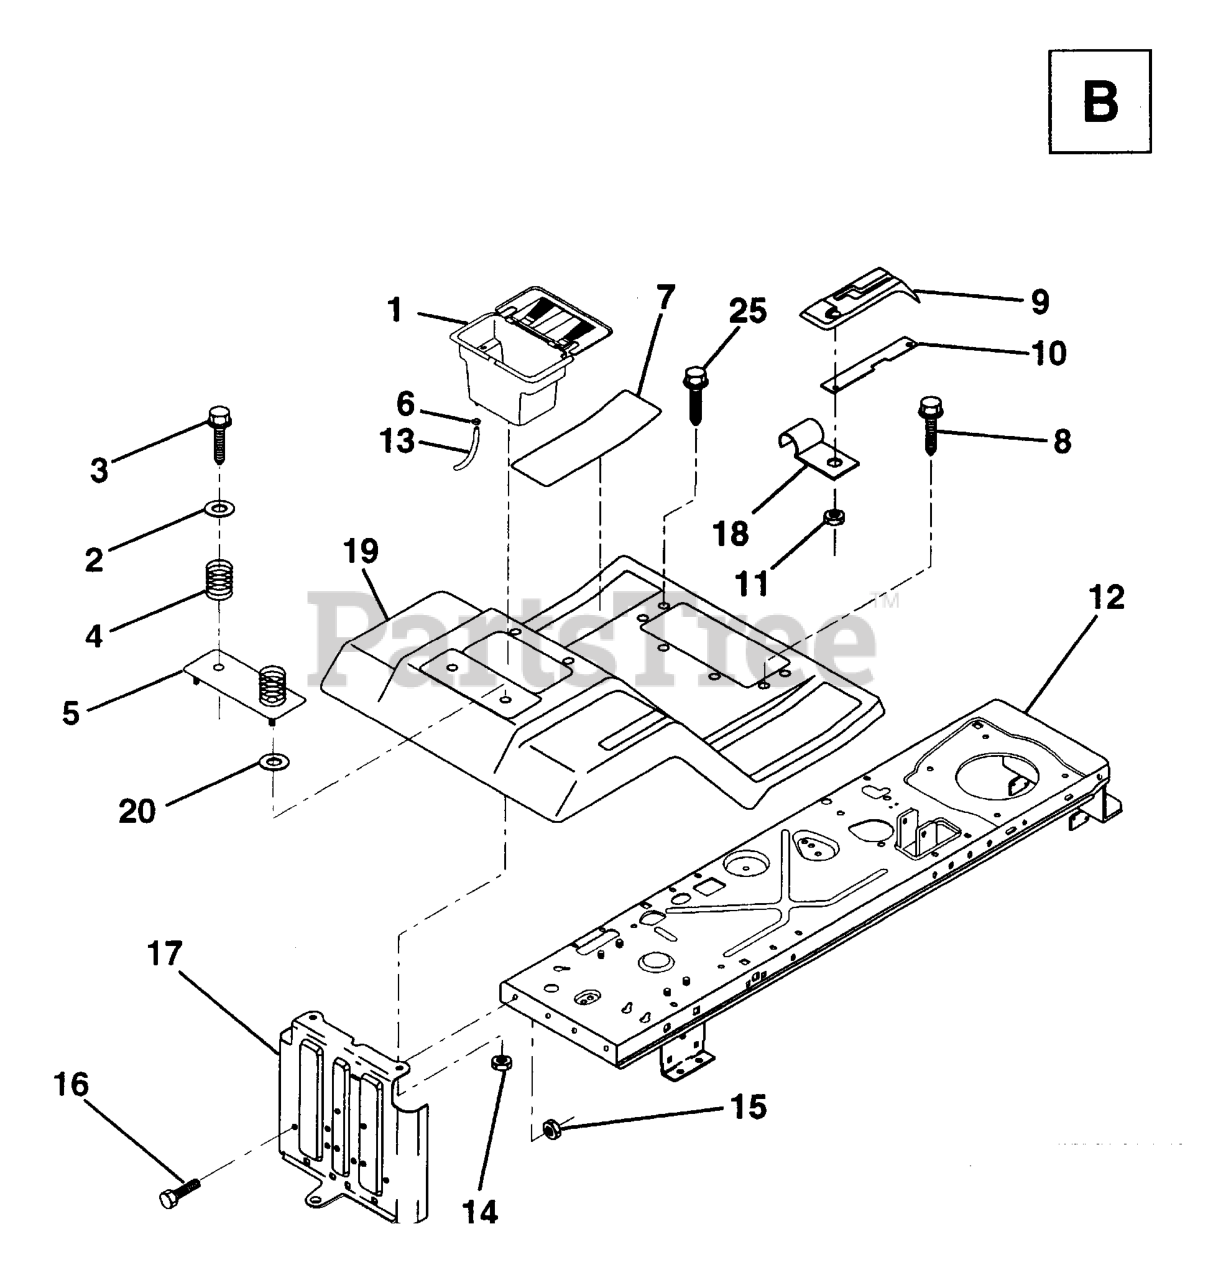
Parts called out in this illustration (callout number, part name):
1	CASE BATTERY
2	WASHER
3	SCREW
4	SPRING COMPRESSION
5	PLATE ASM BATTERY
6	HOSE CLAMP T
7	PAD FOOTREST
8	SCREW.THDROL.5/16-18X3/4.TTY
9	CONSOLE SHT CONTR
10	BAR, SHIFT LOCK
11	NUT.PUSH.3/16
12	FRAME ASSY NLA
13	TUBE BATTERY DRAIN
14	NUT
15	LOCKNUT
16	BOLT
18	CLIP,INSULATOR
19	FENDER/FOOTREST
20	WASHER
25	SCREW
